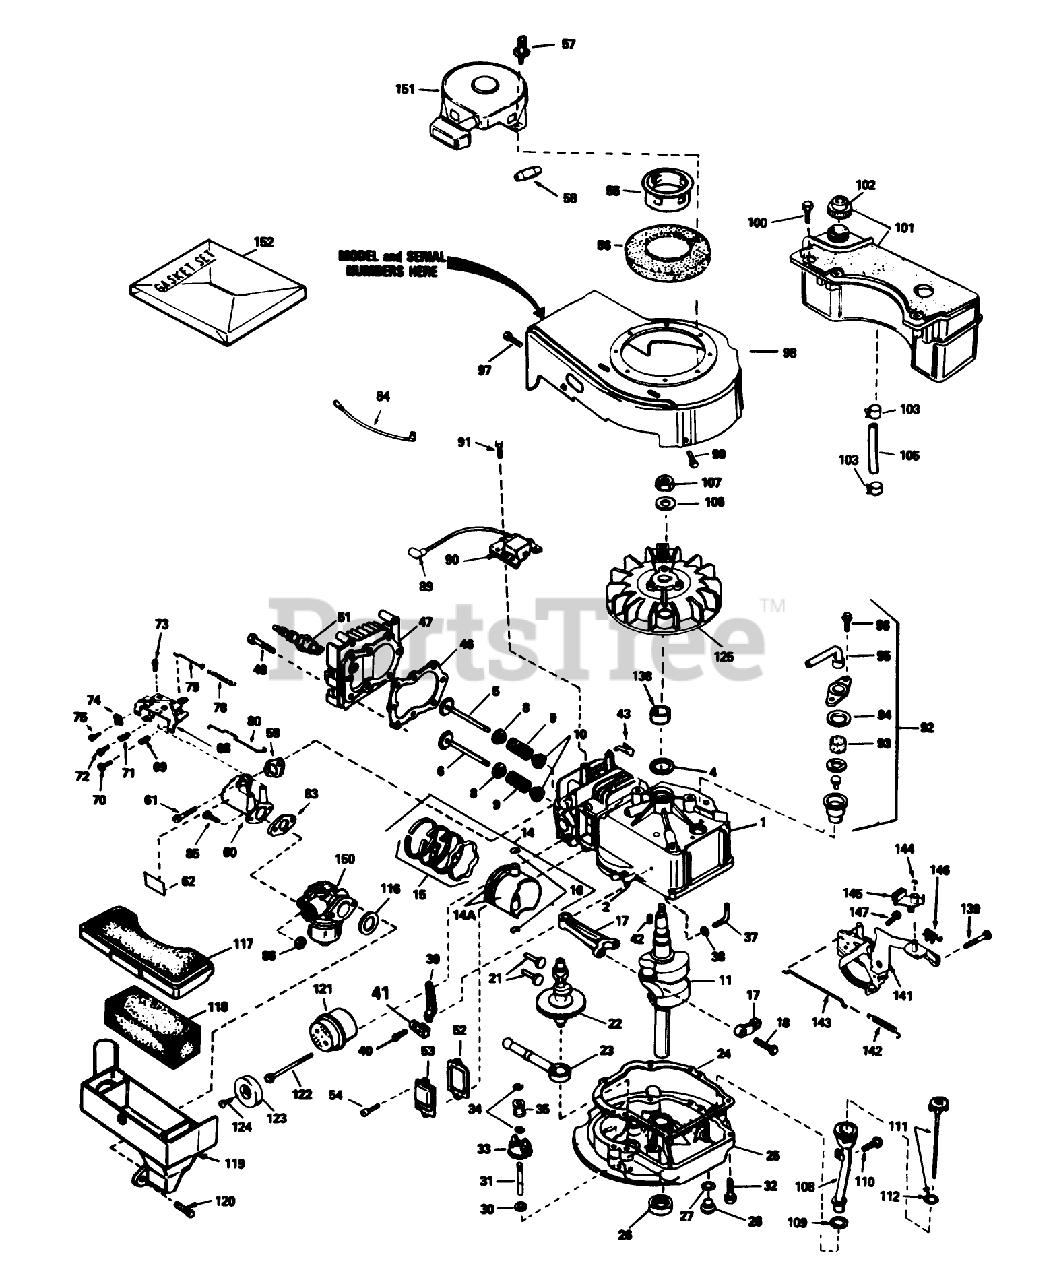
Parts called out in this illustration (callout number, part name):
1	Cylinder Assembly (Incl. Ref. #2, 4, 94 96)
2	Pin-Dowel
4	Seal-Oil
5	Valve, Intake (Std.) (Incl. Ref. #40)
5	Valve, Intake (1/32" oversize)(Incl. No. 40)
6	Valve, Exhaust (Std.)(Incl. No. 40)
6	Valve, Intake (1/32" oversize)(Incl. No. 40)
8	Cap-Upper Valve Spring
9	Spring-Valve
10	Cap-Valve, Spring
11	Crankshaft
14	Piston-Pin Ring Assy. (Std.)(Incl. Ref. #14A, 15 16)
14	Piston-Pin Ring Assy. (.010 oversize)(Incl. Ref. #14A, 15 16)
14	Piston-Pin Ring Assy. (.020 oversize)(Incl. Ref. #14A, 15 16)
14A	Piston Pin Assy. (Std)(Incl. Ref. #16)
14A	Piston Pin Assy. (.010 oversize) (Incl. Ref. #16)
14A	Piston Pin Assy. (.020 oversize) (Incl. Ref. #16)
15	Piston Ring Set Std.
15	Piston Ring Set .010 O.S.
15	Piston Ring Set .020 O.S.
16	Ring-Retaining, Piston Pin
17	Rod Assy., Connecting (Incl. Ref. #17)
18	OA Bolt-Connecting Rod
21	Lifter-Valve
22	Camshaft(Mech.Comp. Release)
23	Oil Pump ASM
24	Gasket, Mounting
25	Flange Assy.-Mounting (Incl. Ref. #26, 27, 28 31)
26	Seal Oil
27	Gasket-Oil Drain
28	Plug Oil Drain
30	Washer-Flat
31	Shaft-Governor
32	Screw (1/4-20 x 1-1/4)
33	Governor Gear ASM
34	Ring-Retaining
35	Spool-Governor
37	Rod, Governor (Incl. No. 36)
38	Washer-Flat
39	Governor Lever
40	Screw
41	Clamp-Lever, Governor
42	Key-Flywheel
43	Clip-Wire
46	Gasket-Cylinder Head
47	2025A67 ADD.ASSEMBL
48	Screw (5/16-18x1-1/2)
51	Plug, Spark (Autolite 458, Champion J-19LM or equiv.)
52	Gasket-Breather
53	Cover-Valve
54	Screw
55	Cup-Starter
56	Screen-Starter
57	Pop Rivet (Can be purchased locally)
58	Retainer-Starter Rope
59	Gasket-Intake
60	Pipe-Intake (Incl. Ref. #59)
61	Screw (1/4-20 x 1)
62	Decal-Primer
68	Control Assy.-Remote Speed (Incl. Ref. #69 thru 72 76)
69	61709/GIL1515A/95-5
70	Screw
71	Spring-Compression
72	Screw
73	Screw (10-24 x 9/16)
74	Conduit
75	Screw (10-32 x 3/8)
78	Spring Governor
79	2035A67 ADD.ASSEMBL
80	Link-Throttle
83	Gasket
84	Ground Wire
86	Nut and Lock Washer (1/4-28)
89	Cover-Spark Plug
90	Solid State
91	Screw
92	Breather Assy. (Incl. Ref. #46 thru 51)
93	Element-Breather
94	Gasket-Breather
95	Tube, Breaker
96	Screw (10-24 x 9/16)
97	Screw (10-24 x 9/16)
98	Housing-Blower
99	Screw (1/4-20 x 1/2)
100	Screw (10-32 x 35/64)
101	Tank Assembly-Fuel (Incl. Ref. #102)
102	Cap-Fuel
103	Clamp-Line, Fuel
105	Line-Fuel
106	Washer-Belleville
107	Nut-Flywheel
108	Tube-Oil Fill
109	Gasket
110	Screw (10-32 x 1/2)
111	Dipstick-Oil (Incl. Ref. #112)
112	O-Ring
116	Gasket-Cleaner, Air
117	Cover Air Cleaner
118	Filter-Air Cleaner
119	Body Air cleaner
120	Screw
121	Muffler (Incl. Ref. #122)
122	Screw
123	Cover-Muffler
124	Screw
125	Flywheel
138	Spacer
139	Screw (1/4-20 x 3/8)
141	Cylinder Assy. (Incl. #24)
142	Spring-Extension
143	Link-Control
144	Ring-Retaining
145	Lever-Brake
146	Terminal
147	Screw-Hex. Hd.
150	Carburetor (Incl. Ref. #83)
151	tarter-Rewind
152	Gasket Set
